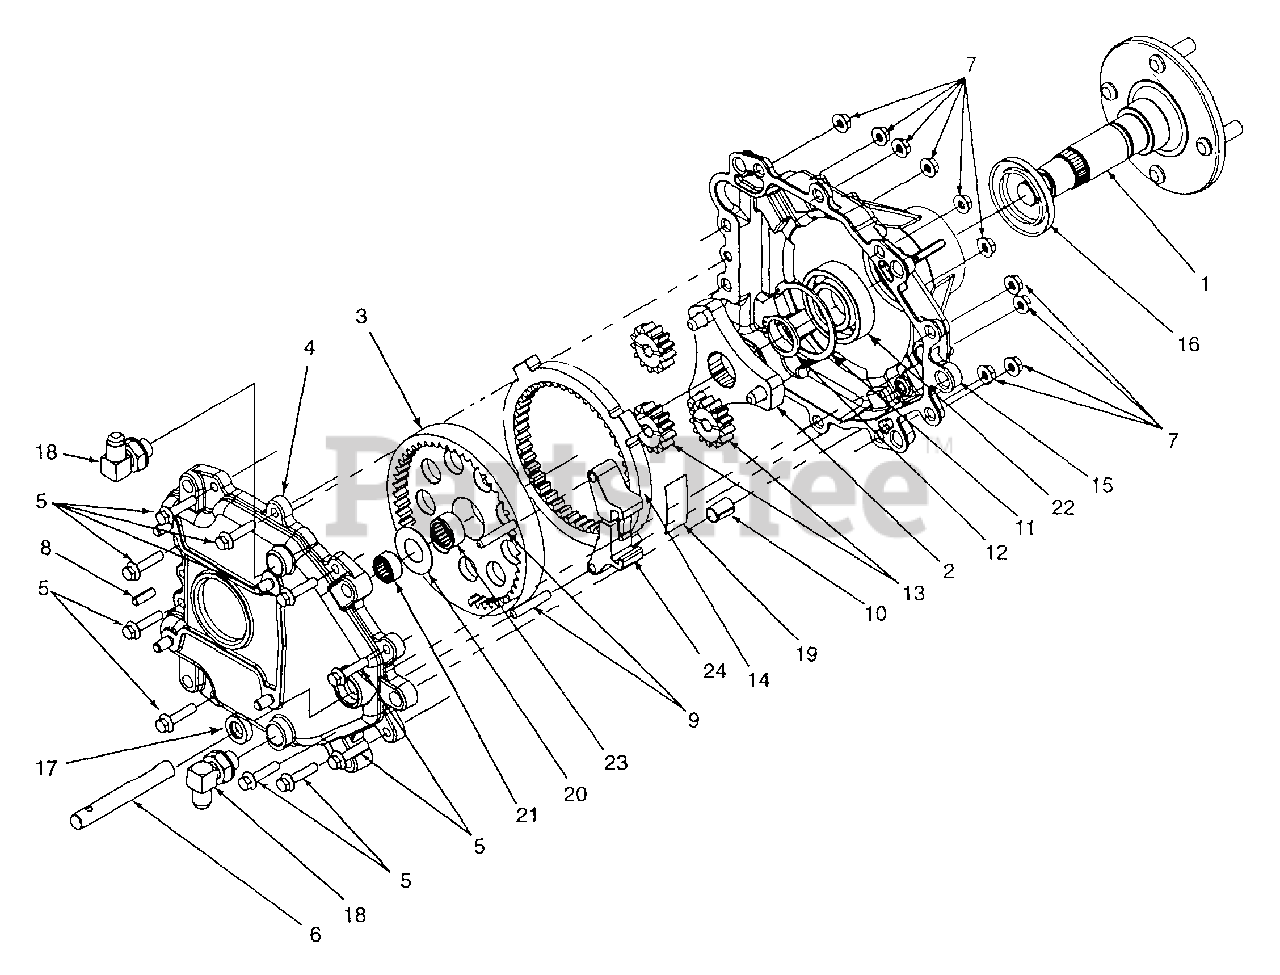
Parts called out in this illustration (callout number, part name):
1	Axle Assembly Stud, Ribbed Neck
2	Carrier Assembly, Output
3	Gear Assembly, 51T Internal & 20T
4	Housing Ass'y, Inner
5	Screw, Hex Wash. Hd. 1/4-20 x 1-1/8
6	Shaft, Brake
7	Nut, Hex Flange Lock, 1/4-20
8	Pin, Roll, .25 x .75
9	Pin, Dowel, .250 x 1.50
10	Bushing, Dowel
11	Ring, Inverted Retaining
12	Ring, Snap, 1.189 Dia. Shft.
13	Gear, Spur, 13T
14	Gear, Ring, 46T
15	Housing
16	Seal, Oil
17	Seal, Oil
18	Fitting, Elbow, 3/8 x 3/8
19	Spring, Brake Shoe
20	Washer, Shim, .76 x 1.5 x .030
21	Bearing, Needle
22	Bearing, Ball
23	Bearing, Needle
24	Brake Shoe
